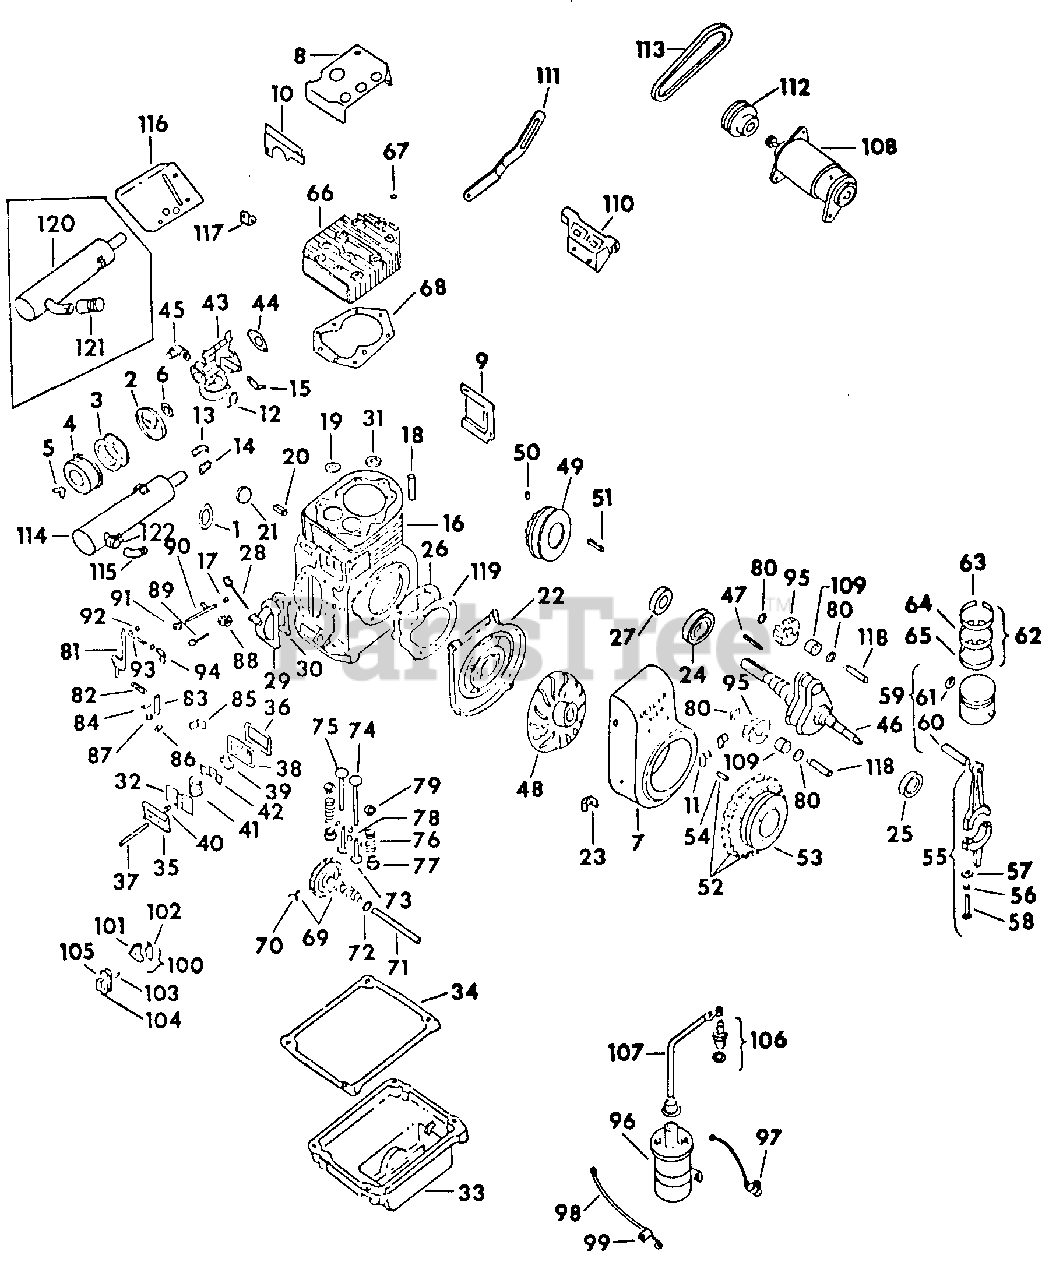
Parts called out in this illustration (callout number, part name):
1	Nut, Exhaust Muffler Elbow Lock
2	Base, Air Cleaner
3	Element, Air Cleaner Filter
4	Cover, Air Cleaner
5	Nut, Air Cleaner Wing
6	Gasket, Air Cleaner
7	Housing Assy, Blower
8	Baffle, Cylinder Head Air
9	Baffle, Cylinder Air
10	Baffle, Housing Side Air
11	Clip, Throttle Cable
12	Clip, Choke Cable
13	Bracket, Throttle
14	Clip, Throttle Cable
15	Bracket, Choke
16	Block, Cylinder
17	Bearing, Needle
18	Guide, Valve
19	Insert, Exhaust Valve
20	Shaft, Governor
21	Plug, 1-1/8 Expansion (Crankcase)
22	Plate, Crankcase Brg
24	Bearing, Crankcase Ball
25	Seal, Front Plate Oil
26	Gasket, Bearing Plate, .10
27	Seal, Crankcase Rear Oil
29	Cover, Camshaft
30	Gasket, Camshaft Cover
31	Insert, Intake Valve
32	Gasket, Valve Cover
33	Base, Oil Pan
34	Gasket, Oil Pan Base
35	Cover, Breather
36	Gasket, Breather
37	Stud, Breather Cover
38	Plate Assy, Breather
39	Reed, Breather
40	Seal, Breather
41	Filter, Breather
42	Baffle, Breather
43	Carburetor Assy
44	Gasket, Carburetor
45	Elbow, Carburetor to Fuel Line
47	Key, 3/16 X 3/8 Sq Parallel
49	Pulley w/Clutch Drive Plate, Flywheel
50	Screw, Flywheel Pulley Set
51	Key, 1/4 X 7/8 Sq Parallel
52	Cup Assy, Flywheel Drive
53	Screen, Drive Cup Grass
54	Pin, Flywheel Drive Cup
55	Rod Assy, Connecting, Std
56	Washer, Connecting Rod Lock
57	Washer, Connecting Rod
58	Screw, Connecting Rod
59	Piston Assy, Std
60	Pin, Piston
61	Retainer, Piston Pin
62	Ring Set, Piston, Std
63	Ring, Top Compression
64	Ring, Center Compression
65	Ring, Oil Control
66	Head, Cylinder
67	Washer, Cylinder Head
68	Gasket, Cylinder Head
69	Camshaft Assy
70	Spring, Camshaft Actuating
71	Pin, Camshaft
72	Shim, Camshaft, .005
73	Tappet Assy, Valve
74	Valve, Intake
75	Valve, Exhaust
76	Spring, Valve
77	Rotator, Valve
78	Keeper, Valve Spring
79	Retainer, Valve Spring Upper
81	Lever, Governor
82	Spring, Governor
83	Bracket, Speed Control
84	Clamp, Control Bracket
85	Bracket, Adjusting Screw
86	Spacer, Adjusting Screw
87	Washer, Adjusting Screw Spacer
88	Gear Assy, Governor
89	Pin, Governor Stop
90	Shaft Assy, Governor Cross
91	Bushing, Cross Shaft
92	Rod, Ball Joint Throttle
93	Retainer, Throttle Rod
94	Joint, 10-32 X 1/4 Ball
95	Gear Assy, Crankshaft Balance
96	Coil, Ignition
97	Condenser, Ignition Coil
98	Cable Assy, Condenser to Breaker
99	Clip, Condenser to Breaker Cable
100	Breaker & Bracket Assy
101	Breaker Contact Set
102	Bracket, Breaker Point
103	Rod, Breaker
104	Cover, Breaker
105	Gasket, Breaker Cover
106	Plug, Spark (Champion)
107	Kit, Hi-Tension Cable Lead
108	Motor Generator
109	Bearing Assy, Needle
110	Bracket, Motor Generator Mounting
111	Brace, Motor Generator Adjusting
112	Pulley, Motor Generator Drive
113	Belt, Motor Generator Drive
114	Muffler w/Clamp
115	Tube, Exhaust Muffler
116	Baffle, Heat
117	Angle, Hanging Strap
118	Pin, Crankshaft
119	Gasket, Bearing Plate
120	Muffler, Exhaust
121	Nipple, 1 X 1-1/4 Pipe
